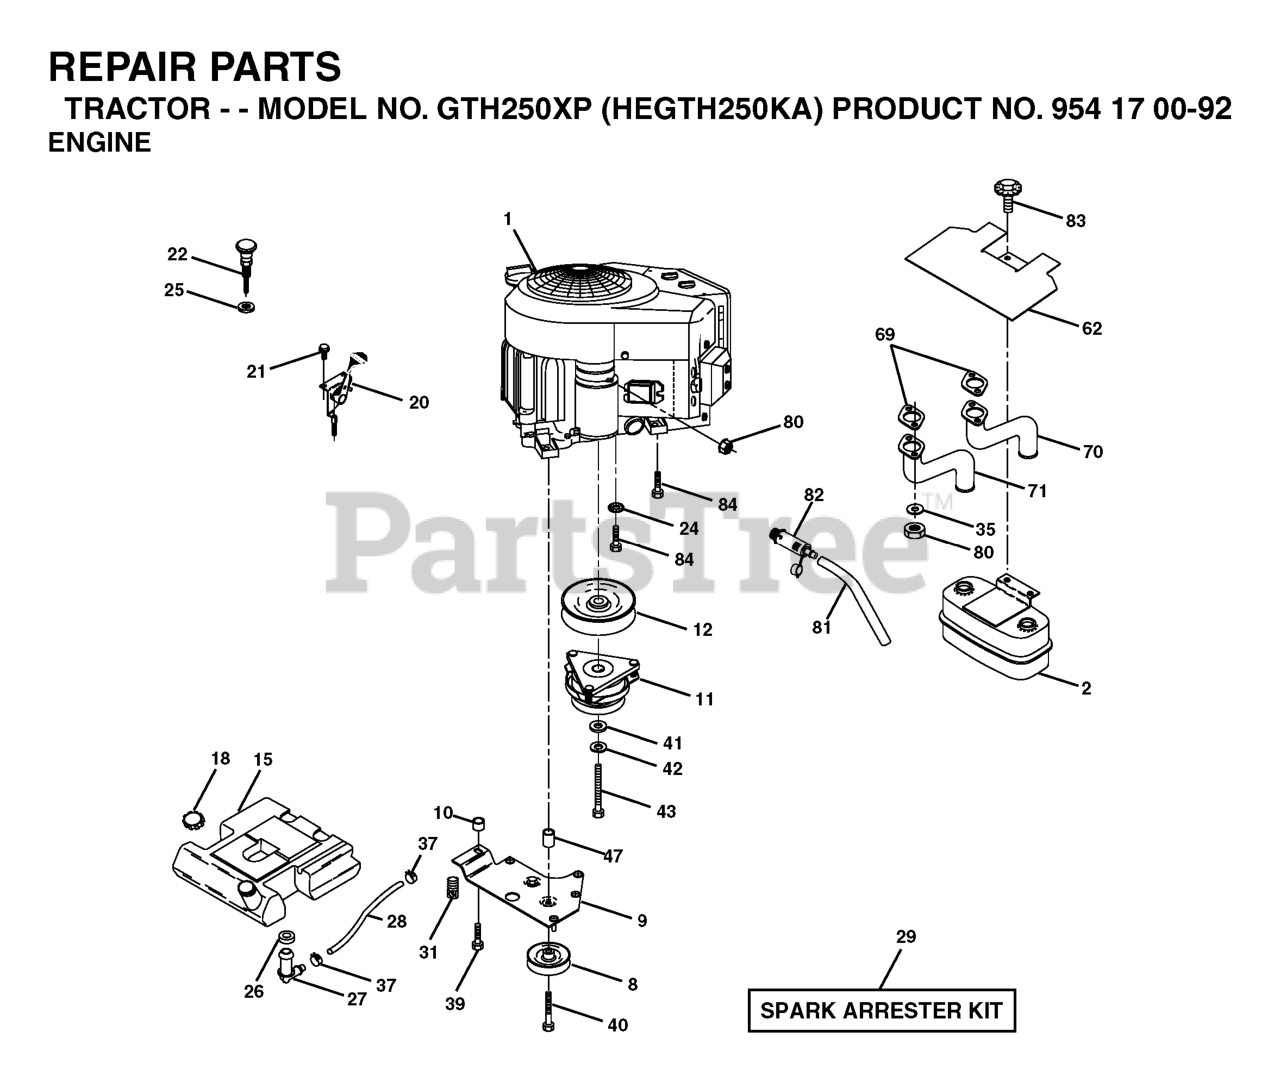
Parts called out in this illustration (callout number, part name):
2	MUFFLER.TWIN.CYL.LOW.TONE
8	RP.IDLER GROOVED
9	KEEPER ASM BELT ENGINE
11	CLUTCH MZ ZTR GT.48/54"1.125"
12	PULLEY ENG VGT ELECT CLUTCH
15	TANK.FUEL.5.0 LEFT.FILL.YTGT
18	TANK CAP
20	CONTROL.THROTTLE.COBRA.42"BLK.
21	SCREW
22	CHOKE CONTROL
24	LOCKWASHER
25	Nut Keps 3/8 - 24 UNF
26	BUSHING OUTLET T
27	STEM FUEL TANK
28	FUEL LINE
29	KIT.SPARK ARRESTOR 794945 B&S
35	WASHER.LOCK.HVY.HLCL.SPR.5/16
37	HOSE CLAMP
39	SCREW TT 3/8-16X2-1/4 UNC
40	Screw TT 3/8-16 x 4 unc
42	LOCKWASHER
43	BOLT HEX 7/16-20 X 3.75 GR. 5
62	HEAT SHIELD
70	TUBE EXHAUST LH
71	TUBE.EXHAUST.KAWASAKI.RH
80	FLANGE NUT
81	TUBE, DRAIN OIL ASM.
83	BOLT.5/16-18UNCX3/4 W/SEMS.BLK
84	SCREW 3/8-16 X 1-1/2
